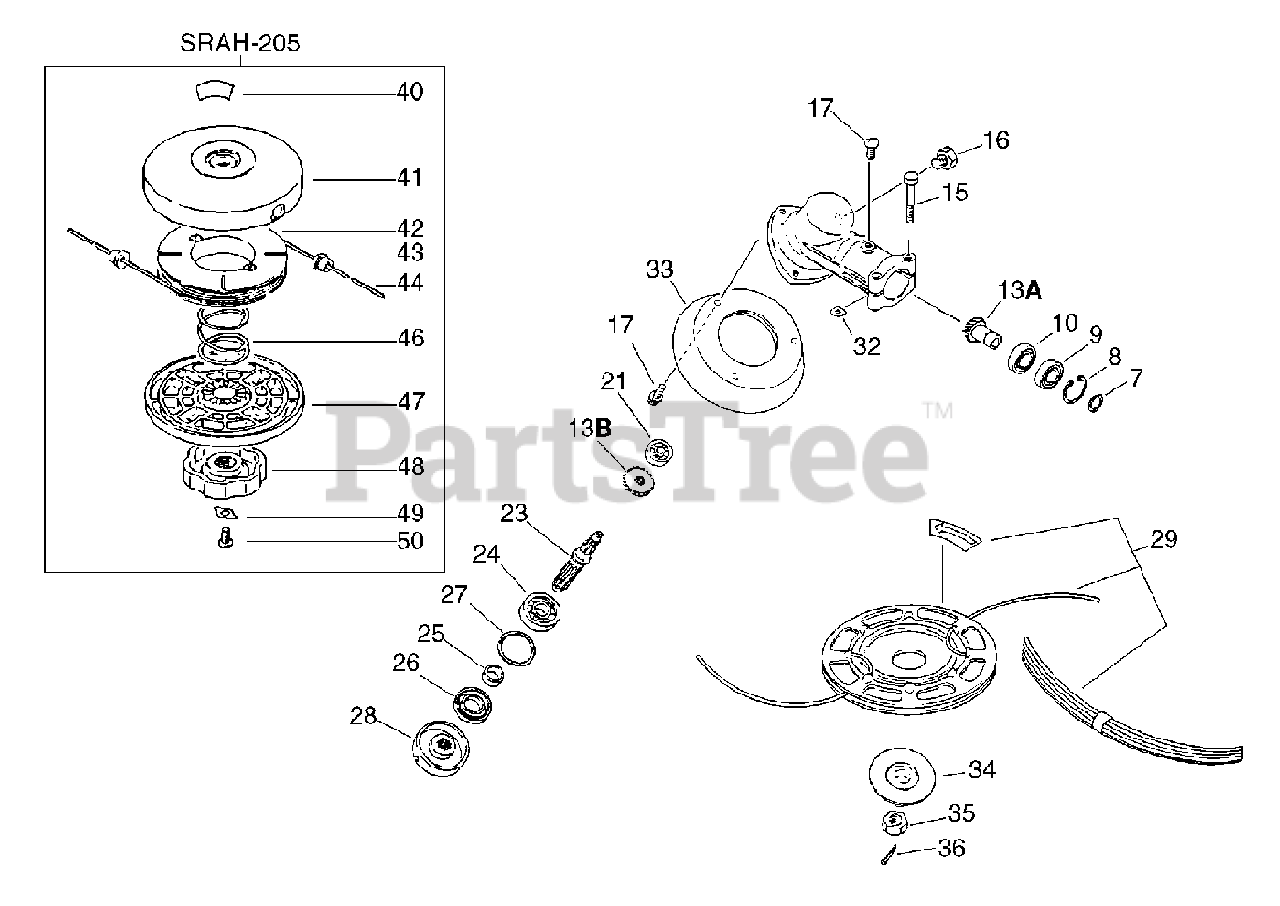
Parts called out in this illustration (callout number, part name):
7	Circlip 10
8	Circlip 22
9	Bearing, Ball 6900Z
10	Bearing, Ball 6900
15	Bolt 5*28 (W/W,SW)
16	Bolt 8* 8
17	Screw 5*10
21	Bearing, Ball 626
23	Shaft, p.t.o.
24	Bearing, Ball 6000
27	Circlip 26
28	Plate, Adapter (U)
29	Cutter Black
32	Washer, Shim
33	Plate, Guard (W\H)
34	Plate, Adapter
35	Nut 10 (L-H)
36	Pin, Split 2*22
40	Label, Caution
41	Drum, Cord Reel
42	Reel, Cord
44	Cord, Nylon(2.4*2.5)
47	Cover, Drum (JY)
48	Knob,Fastener
49	Stopper, Nut
50	Screw 6*10
